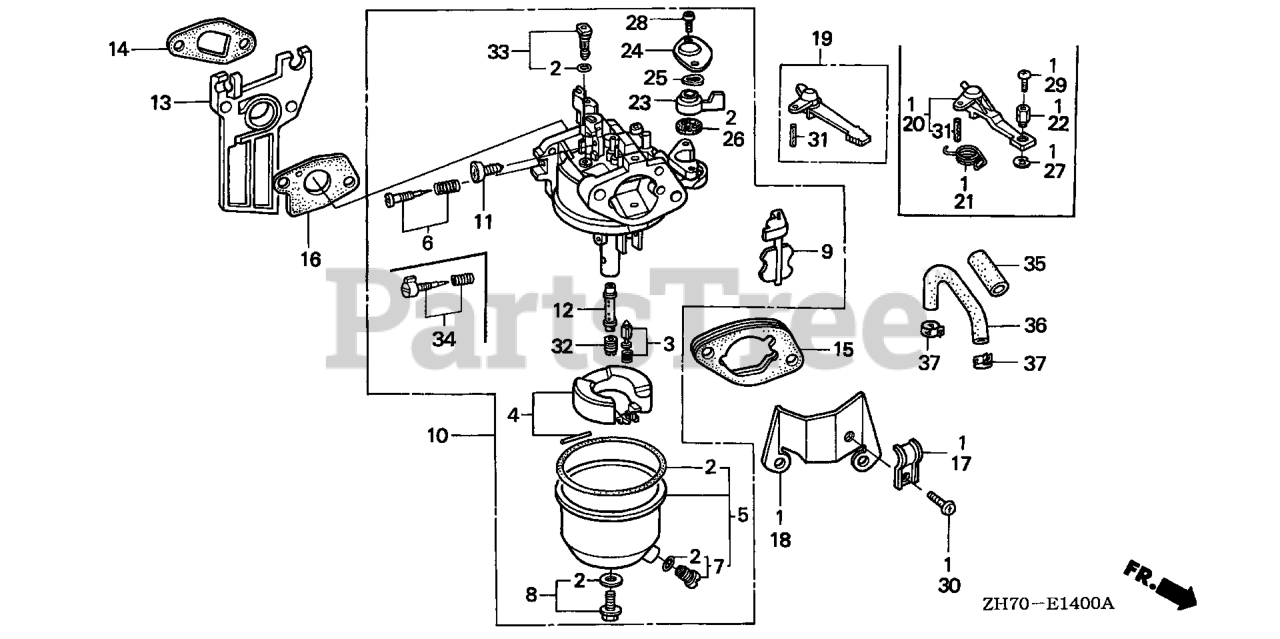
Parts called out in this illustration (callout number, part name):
1	CHOKE KIT, REMOTE CONTROL
2	GASKET SET (CARBURETOR NO.)
3	VALVE SET, FLOAT (CARBURETOR NO.) (SEAT NOT INCLUDED)
4	FLOAT SET
5	CHAMBER SET, FLOAT (CARBURETOR NO.)
5	CHAMBER SET, FLOAT (CARBURETOR NO.) (FOR BE12A A)
6	SCREW SET, PILOT (Honda Code 1441500). (CARBURETOR NO.)
7	SCREW SET, DRAIN (Honda Code 1672187). (CARBURETOR NO.)
8	SCREW SET B
8	SCREW SET
9	CHOKE SET
10	CARBURETOR ASSY. (BE12B C)
11	SCREW, THROTTLE STOP
12	NOZZLE, MAIN (CARBURETOR NO.)
12	NOZZLE, MAIN
13	INSULATOR, CARBURETOR
14	GASKET, INSULATOR
15	SPACER, CARBURETOR
16	GASKET, CARBURETOR
17	HOLDER, CONTROL CABLE Use from Engine SN 2327377.
18	STAY, CHOKE CONTROL
19	LEVER, CHOKE (STD)
20	LEVER, CHOKE (REMOTE)
21	SPRING, RETURN
22	HOLDER, CABLE
23	LEVER, VALVE
24	PLATE, LEVER SETTING (CARBURETOR NO.)
25	SPRING, PETCOCK LEVER (CARBURETOR NO.)
26	GASKET, VALVE
27	CIRCLIP (5MM) Use from Engine SN 2327377.
28	SCREW, PAN (3X6)
28	SCREW, PAN (3X8) (CARBURETOR NO.)
29	SCREW, PAN (4X8)
30	SCREW, PAN (5X8)
31	PIN, SPRING (2X12)
32	JET, MAIN (#55) (CARBURETOR NO.) Use up to Engine SN BE03A J.
32	JET, MAIN (#58) Use from Engine SN BE30B E.
32	JET, MAIN (#60)
33	JET SET, PILOT (#35)
